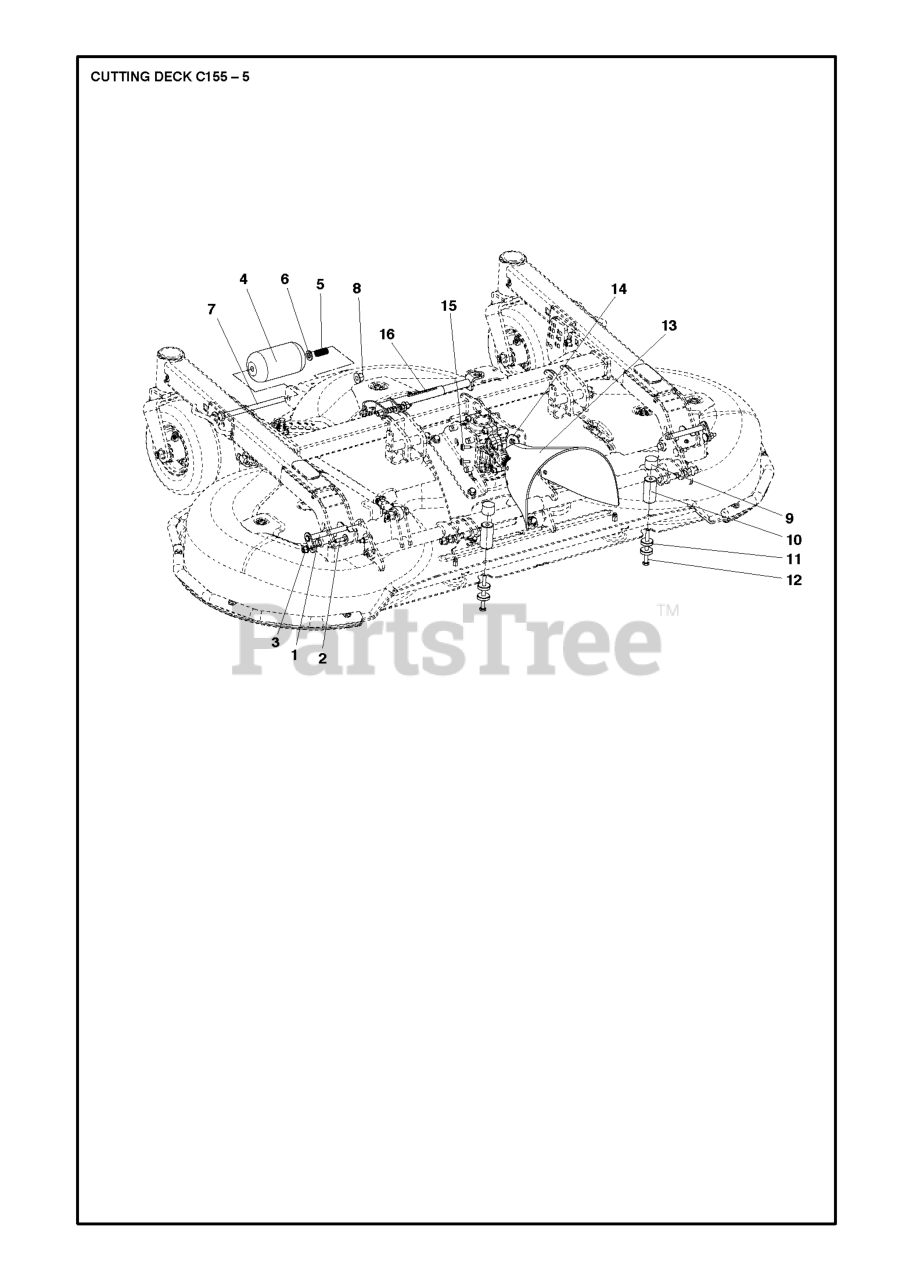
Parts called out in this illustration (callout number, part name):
3	NUT FLANGE
6	WASHER - M12
9	ANTIVIBRATION ELEMENT
